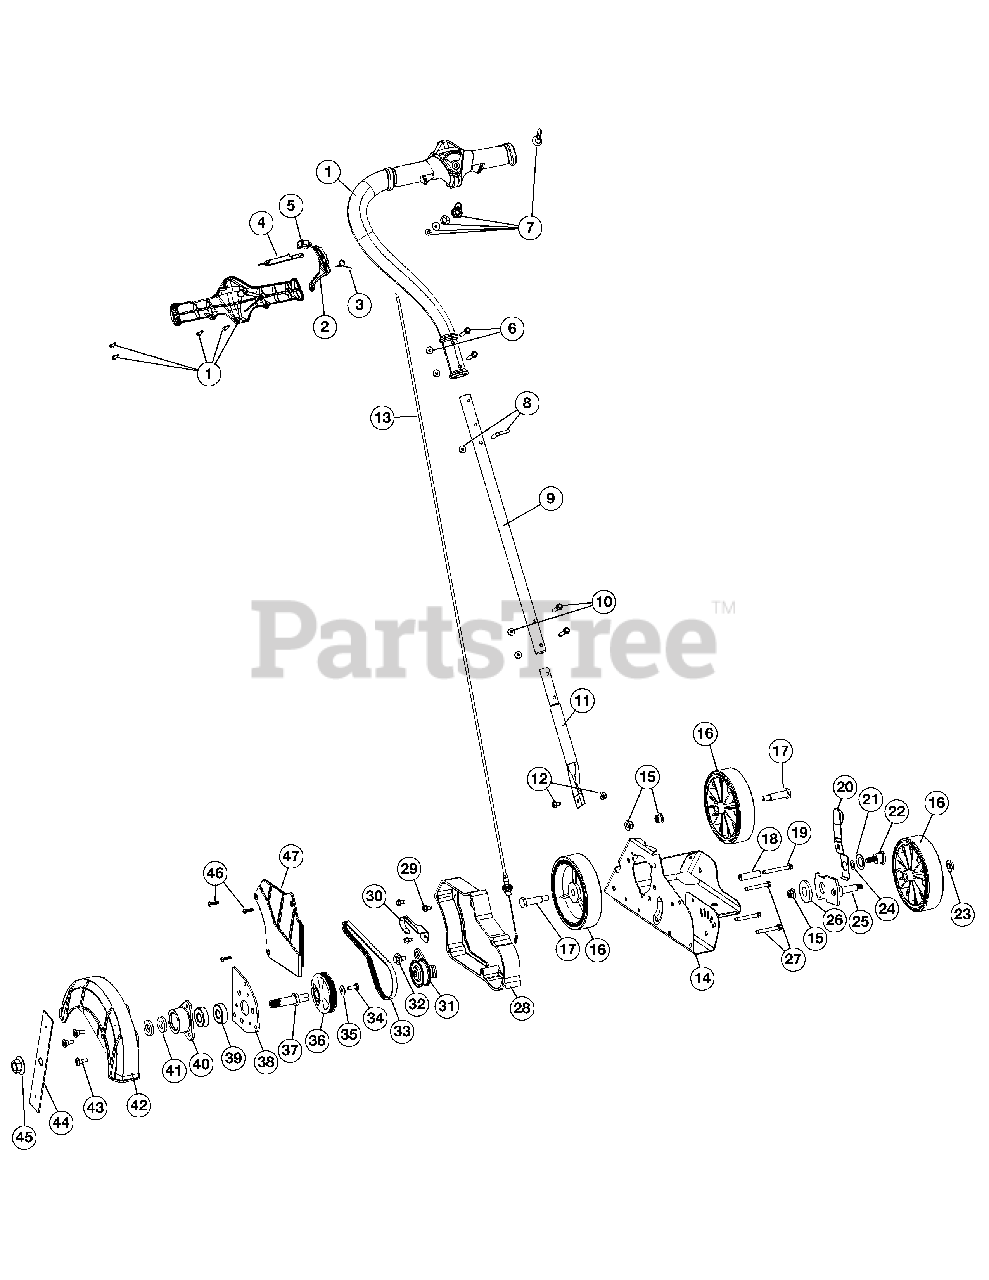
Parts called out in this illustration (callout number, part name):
1	Handle Assembly (includes 2-7)
2	Throttle Trigger
3	Throttle Trigger Spring
4	Blade Lockout Lever
5	Switch Assembly
6	Upper Handle Screw & Nut Assembly
7	Throttle Lever
8	Starter Rope Guide Assembly
9	Middle Handle Assembly (includes 10)
10	Middle Handle Screw & Nut Assembly
11	Lower Handle
12	Lower Handle Screw & Nut Assembly
13	Clutch Cable
14	Edger Frame
15	Lock Nut
16	Wheel
17	Wheel Bolt
18	Spacer
19	Spacer Screw
20	Height Adjustment Lever Assembly
21	Washer
22	Shoulder Screw
23	Nut
24	Washer
25	Pivot Arm
26	Height Adjustment Spacer
27	Spindle Plate Screw
28	Spindle Spacer
29	Screw
30	Belt Retainer
31	Idler Pulley Assembly
32	Shoulder Screw
33	Belt
34	Screw
35	Washer
36	Pulley
37	Blade Spindle
38	Spindle Plate
39	Bearing
40	Bearing Cup
41	Washer
42	Blade Guard
43	Screw
44	Edger Blade
45	Nut
46	Screw
47	Belt Cover
